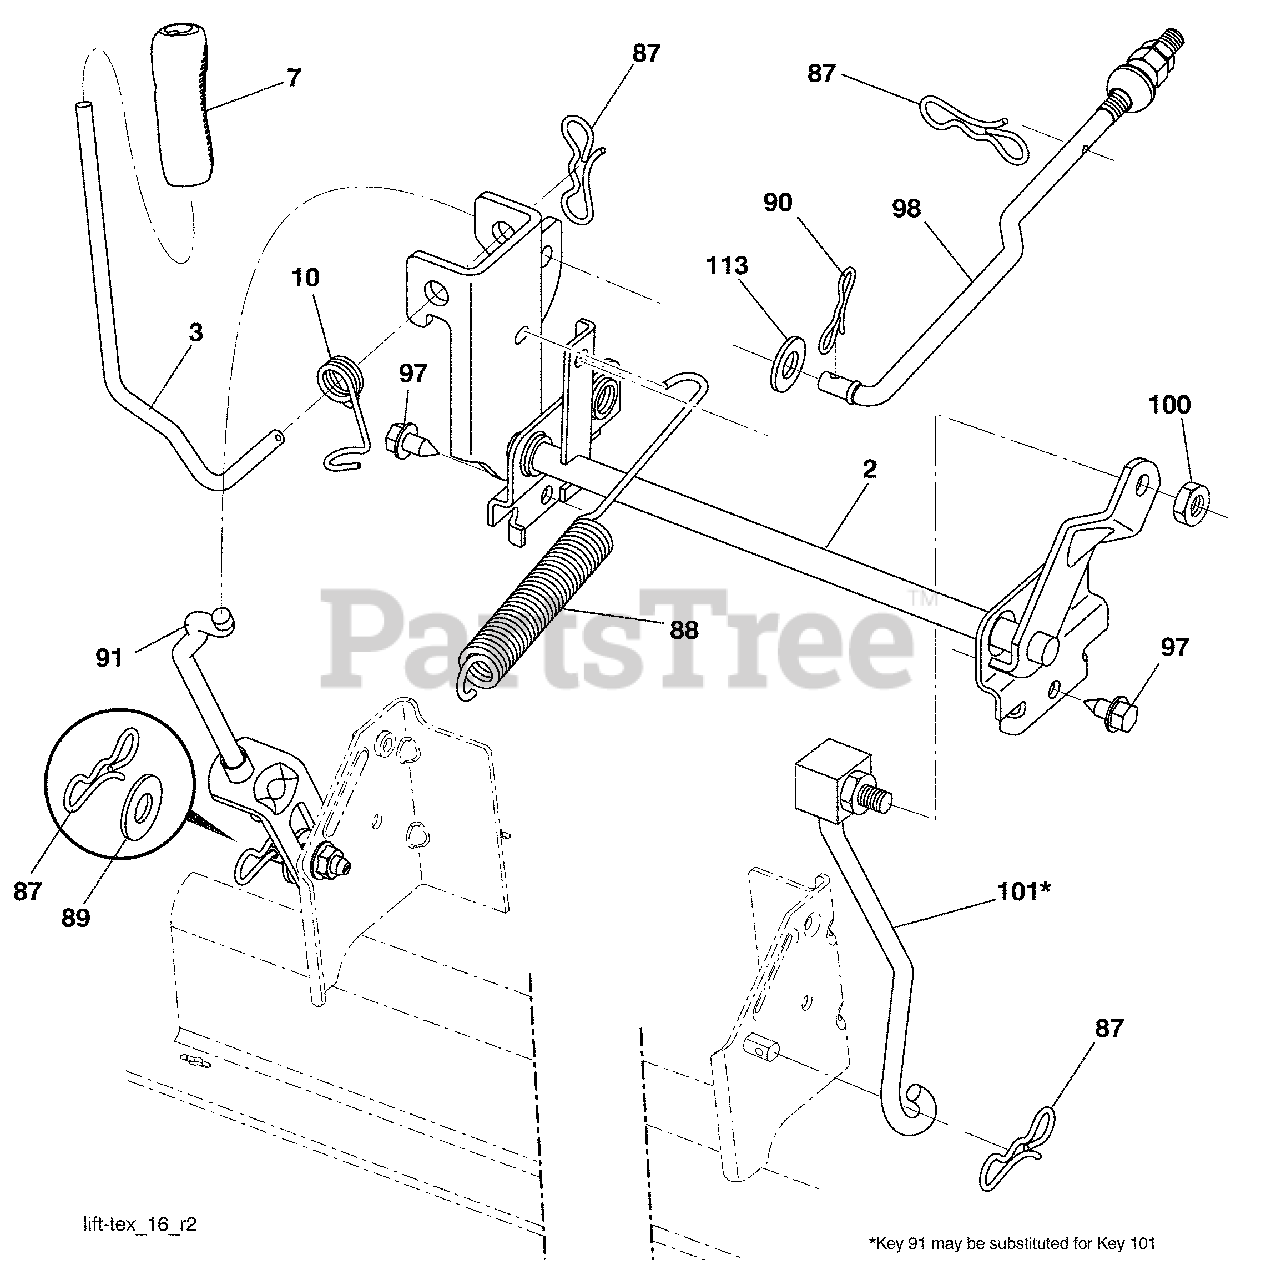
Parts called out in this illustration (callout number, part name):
2	Shaft Asm., Lift
3	Lever Asm., Lift
7	Grip, Lever
10	Spring Torsion
87	Pin Cotter 7/16 Bow Tie Lock
88	Spring Lift Assist
89	Washer Clear Zinc
90	Pin Cotter 5/16 Bow Tie Lock
91	Link Lift Susp Mower Rear
97	Screw 3/8-16 x .75
98	Link Lift Susp. Front Mower
100	Nut Centerlock 3/8-16 unc
101	Link List Asm. FXD
113	Washer 17/32 x 1-3/16 x 12 Ga.
